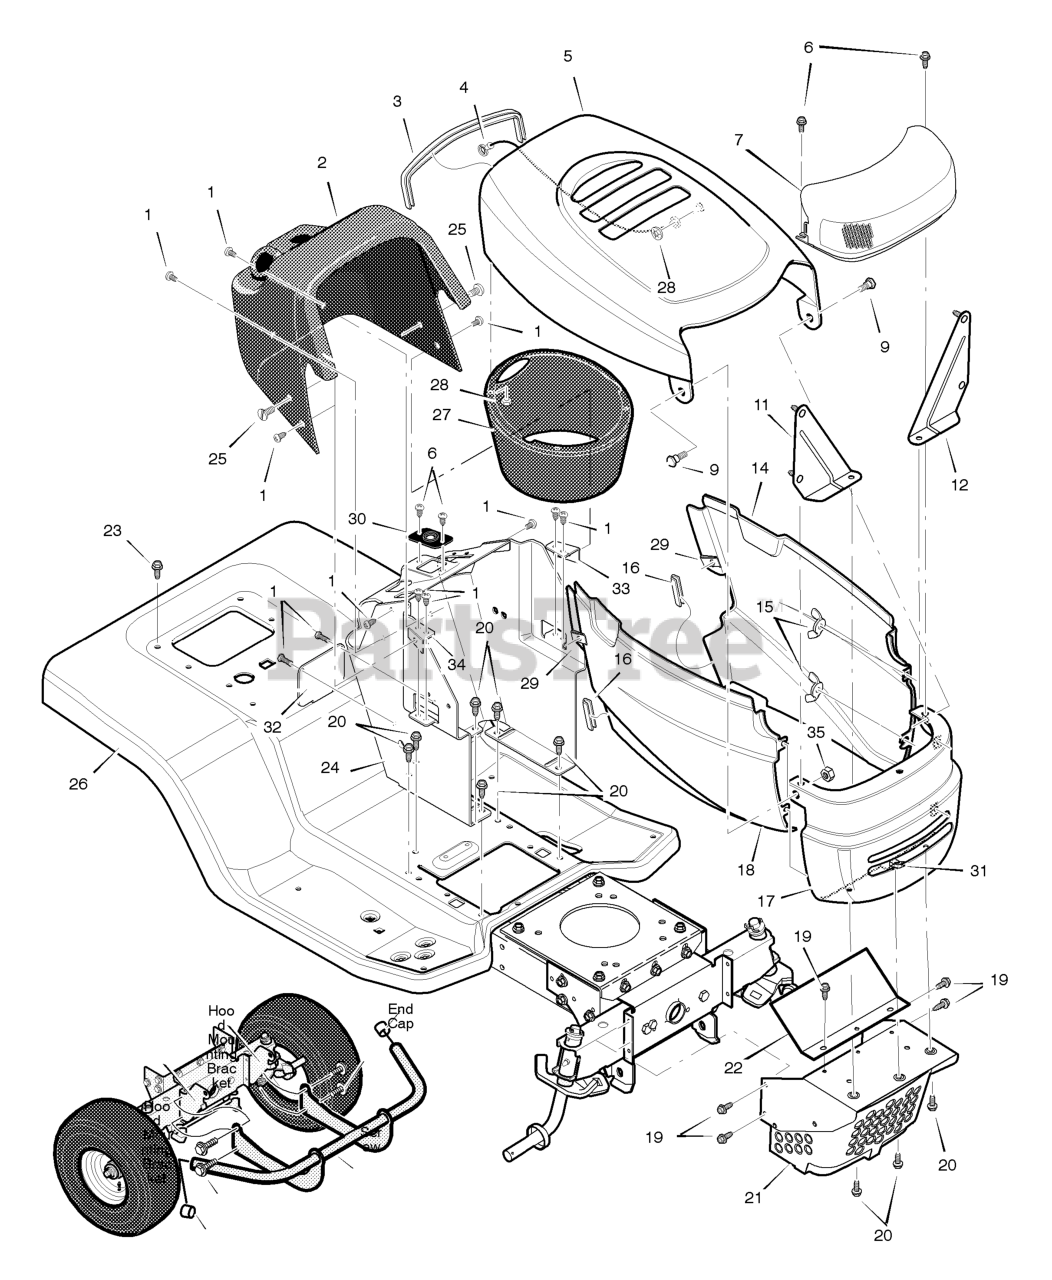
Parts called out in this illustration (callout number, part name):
1	Screw
3	Trim 2.23"
5	Hood Assembly
7	Lens & Reflector Assembly
9	Bolt, Shoulder
11	Brace, Right Grille Assembly
12	Brace, Left Grille Assembly
14	Panel, Left Side
15	Wingnut
16	Trim 0.39"
18	Panel, Right Side
21	Guard Assembly, Muffler
22	Shield, Upper Heat
26	Deck Seat
28	Retainer, Push
29	Cap, Push
30	Bearing, Steering
32	Panel, Access
33	Bracket, Right Console
34	Bracket, Left Console
